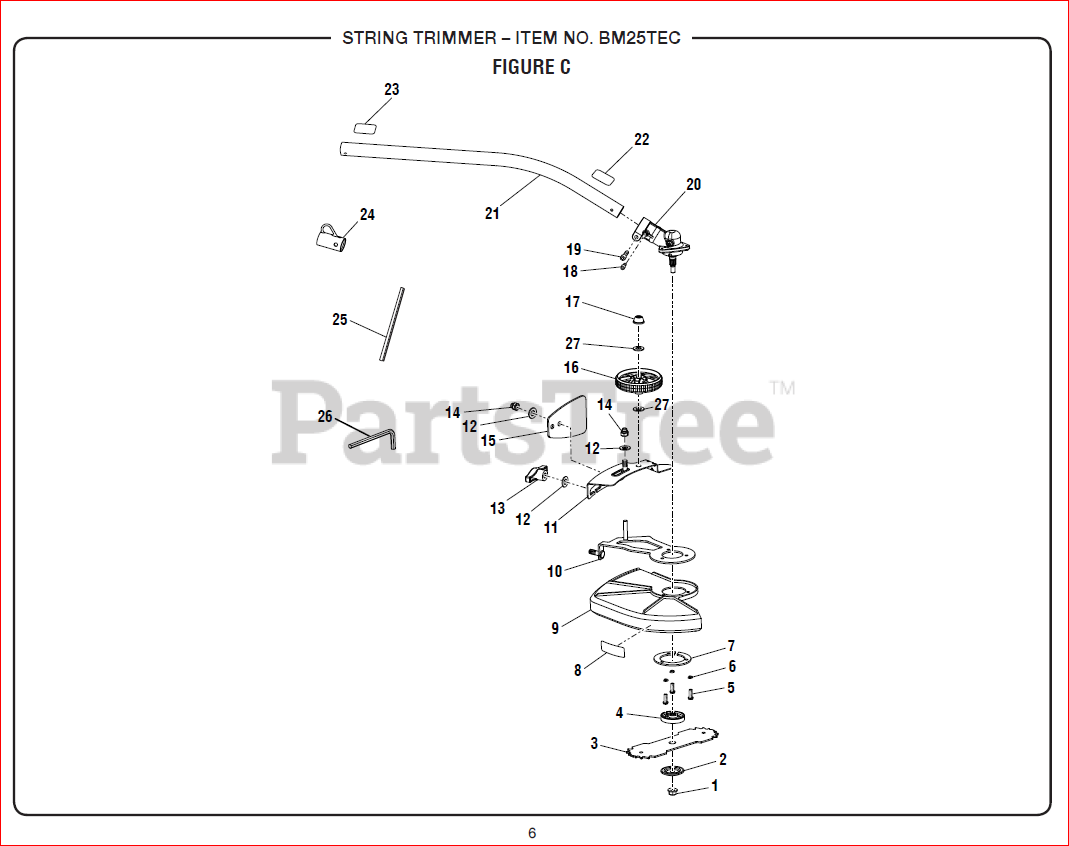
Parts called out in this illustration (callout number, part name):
1	Lock Nut (M8 x 1.25 in., Left Hand Threads)
2	CUPPED WASHER
3	Edger Blade
4	FLANGED WASHER
5	Screw (10-24 x 5/8 in, Hex Hd.)
6	Lock Washer (5 mm)
7	Ring Washer
8	Warning Label (Guard)
9	Blade Guard
10	Main Frame
11	Wheel Frame
12	Washer (10 mm)
13	Adjusting Knob w/Hex Nut
14	Hex Nut with Nylon Cap (5/16-18)
15	Debris Flap
16	Guide Wheel
17	Push Nut (10 mm)
18	Screw (10-24 x 5/8 in. Hex Socket Hd.)
19	Screw (1/4-20 x 1-1/4 in., Hex. Socket Hd.)
20	Gear Head Assembly
21	Drive Shaft Assembly
22	Hot Surface Warning Label
23	Boom Icon Warning Label
24	Storage Hanger Cap
25	Gear Head Locking Tool
26	Hex Key (M4)
27	Washer, ID 11 x OD 18 x 2T
